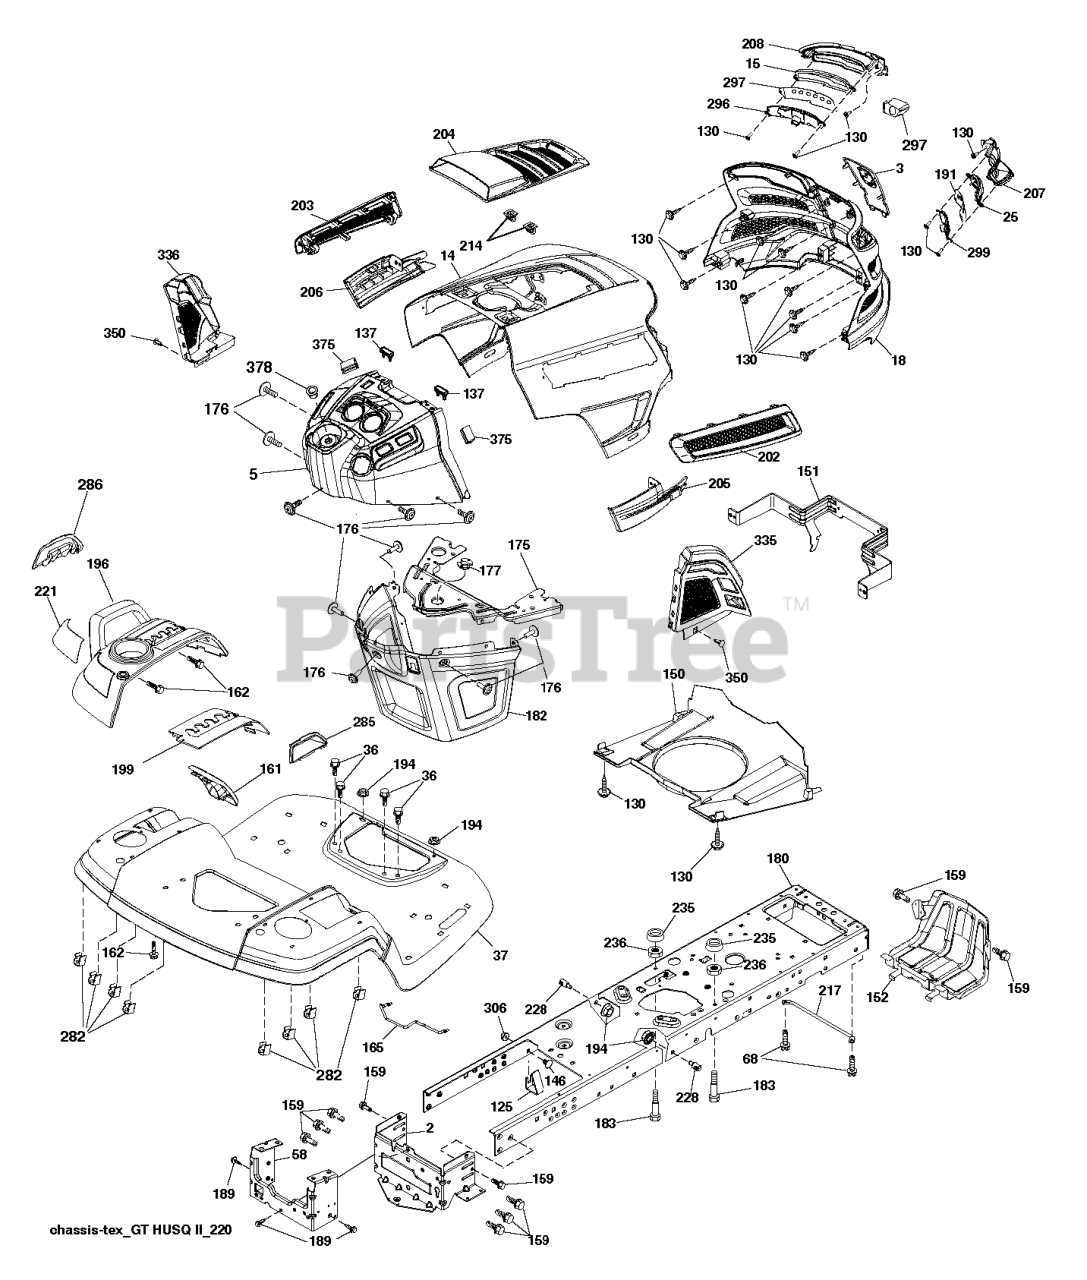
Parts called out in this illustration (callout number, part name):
2	DRAWBAR.LOWER.2PC.18/22
3	APPLIQUE.SUBASM.GT.HUSQ.II
5	DASH.UPR.GT2.DUAL.RD.PTO.MC
14	HOOD.ASM.HUSQVARNA.GT.TEX.ORAN
15	LED LIGHT.LH
18	GRILLE SUBASM.GT.II.LOW.HDLGHT
25	LENS.RH
36	SCREW 5/16"
37	FENDER.PNT.TX.GT.CH/FW/DL.HUSQ
58	DRAWBAR.UPPER.2PC,LRG.FENDER
68	SCR 5/16-18 X 1/2 SELFTAP ZN
125	CLIP.FUEL.LINE
130	SCREW.#10 X 0.750.BOS
137	BUMPER DASH
146	BOLT.RDHD.SHT.SQNK.3/8-16X5/8
150	AIR.DUCT.GTV.BLACK
151	BRACKET.PIVOT.HOOD.GT.HUSQ.II
152	SHIELD.BROWNING.PNT.GT.V2
159	SCREW, 3/8-16X3/4
161	CONSOLE.WINDOW.FUEL.HUSQ.GT
161	WINDOW.FUEL.LT.HUSQ.TEX.498
161	WINDOW.FUEL.LT.TEX.GREY
162	SCREW 1/4X20
162	SCREW.HI-LO.CONSOLE
165	SUPPORT.TANK.REAR.B/TE
175	PLATE.PNT.CROSSMEMBER.HUSQ/PRE
176	SCREW.#10-24X5/8.RN.QU
177	BUSHING STEERING
180	CHASSIS.LT/GT.BOLTED
182	DASH.LOWER.COMMON.12V.ADAPTOR
183	BOLT.5/16-18X1-1/4 FULL THD
189	SCREW
191	INSERT INFLECT.RH
194	NUT LOCK HEX FLANGE 5/16-18
196	CONSOLE.DECK.LIFT.R.SDFL.HUSQ
196	CONSOLE.ASM.DECKLIFT.HUSQGT.DL
199	PLATE.DECK.LIFT.HUSQVARNA.GT
202	VENT.SIDE.RH.GT.HUSQ.II.
203	VENT.SIDE.LH.GT.HUSQ.II.498
204	VENT.TOP.HUSQ.GT2
205	SIDE.TRIM.RH.GT.HUSQ.II
206	SIDE.TRIM.LH.GT.HUSQ.II.GRAY
207	BEZEL GT2 LED RH W/ LOWER.ATT
208	BEZEL GT2 LED LH W/ LOWER ATT
214	CLIP.RETAINER.TINNER.
217	ROD.PIVOT.HOOD
221	REFLECTOR.LH.TEX GT HU
228	STUD.FASTNER.W/ANTI-ROTATE
235	SPACER FENDER
236	NUT.CENTERLOCK.5/16-
282	CLIP.RETAINER.CONSOLE.LT.HUSQ
285	CONSOLE INSERT RH
286	CONSOLE.INSRT.LH.HUSQ.LT.BLACK
296	LED LIGHT.LH
297	INSERT REFECT LH
299	LED LIGHT.RH
306	NUT LOCK FLG 3/8-16 UNC
335	COVER.LOWER.DASH.RH.BLACK
336	COVER-LH.LOWER.DASH.GT2.BLACK
350	CLIP.X-MAS.TREE
375	BUMPER CLIP-ON. DASH 1"
378	BUSHING FLANGE; PLASTIC
